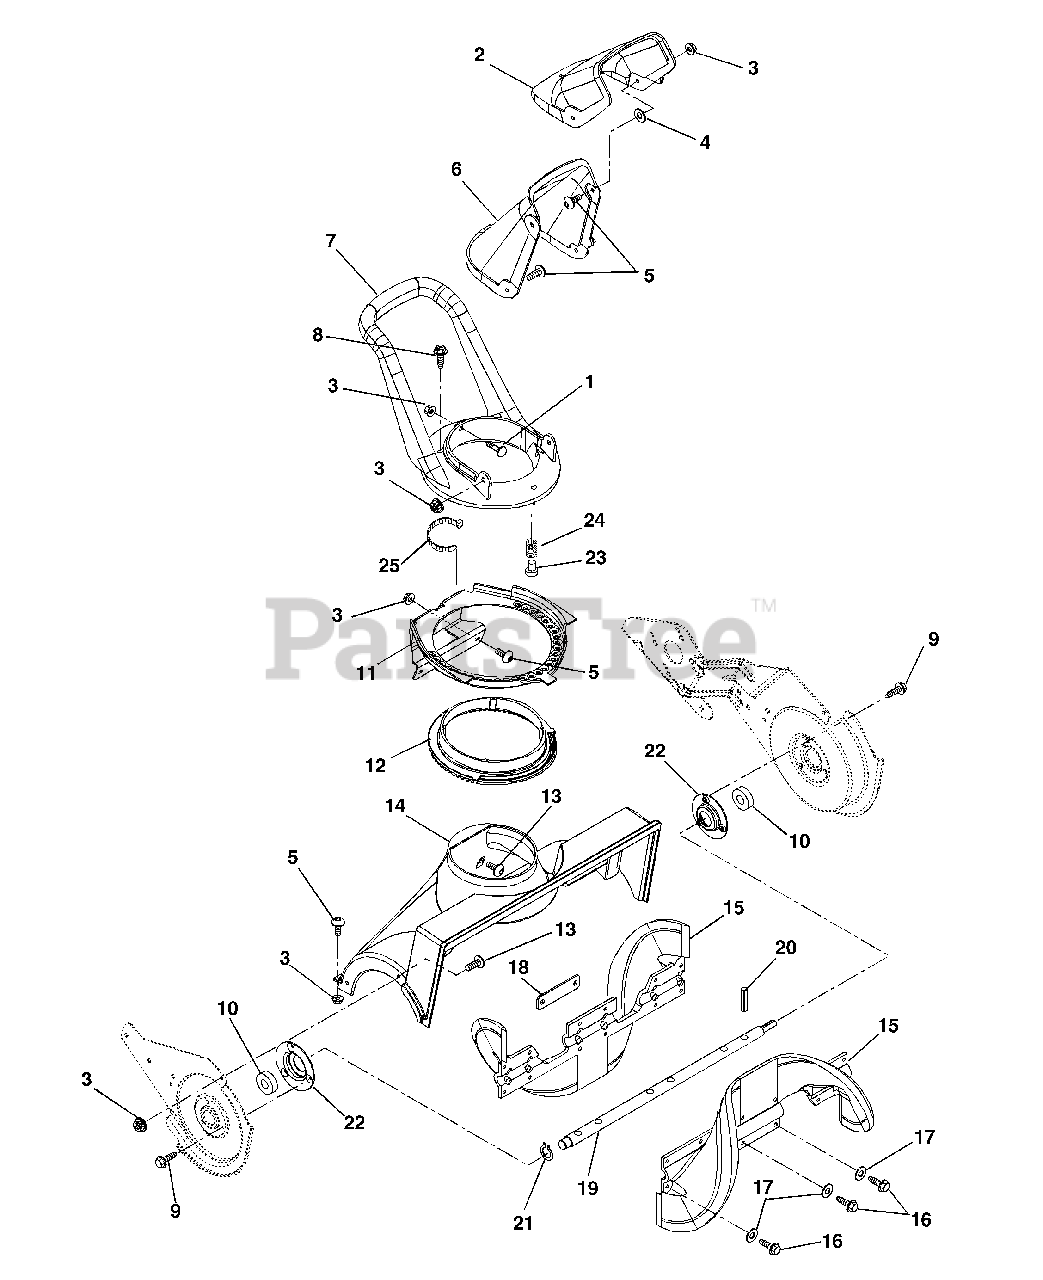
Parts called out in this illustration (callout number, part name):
1	@BLT-RDHDSQNK .25-20X.75 G5YZ
2	DEFLECTOR-DISCHARGE CHUTE ASSY
3	NUT-LK-FLG .250-20 PL BLK
4	WSHR-FL-RBR .31X1.25X.06
5	SCR-MCH .25-20X.75 TXTR YWZC
6	CHUTE-DISCHARGE ASSY
8	SCR TAP 8-18X1.50 SL HWH PL B
9	@SCR-TAP .25-20X.50 HWH TR YWZ
10	BRG-BALL .669X1.575X.47 (6203)
11	BRKT-DISCHARGE CHUTE ROTATION
12	GEAR-DISCHARGE CHUTE SEGMENT
13	SCR-MCH .25-20X.50 TXTR PL
14	HOUSING-IMPELLER ASSY
15	IMPELLER HALF
16	@SCR-TAP .25-20X1.00 HWH TR YZ
17	WSHR-FL-STL .281X1.000X.063
18	PLATE-BOLT,SELF-TAPPING
19	SHAFT-IMPELLER
20	PIN-ROLL .250X1.75 ZINC PL
21	RG-RTNG-EXT .672X.035
22	CUP-BRG
23	RVT- .250 X 1.125 TRUSS YWZC
24	SG-COMP .045X.360X1.75 WLD12.5
25	CABLE TIE LG 5-1/2
